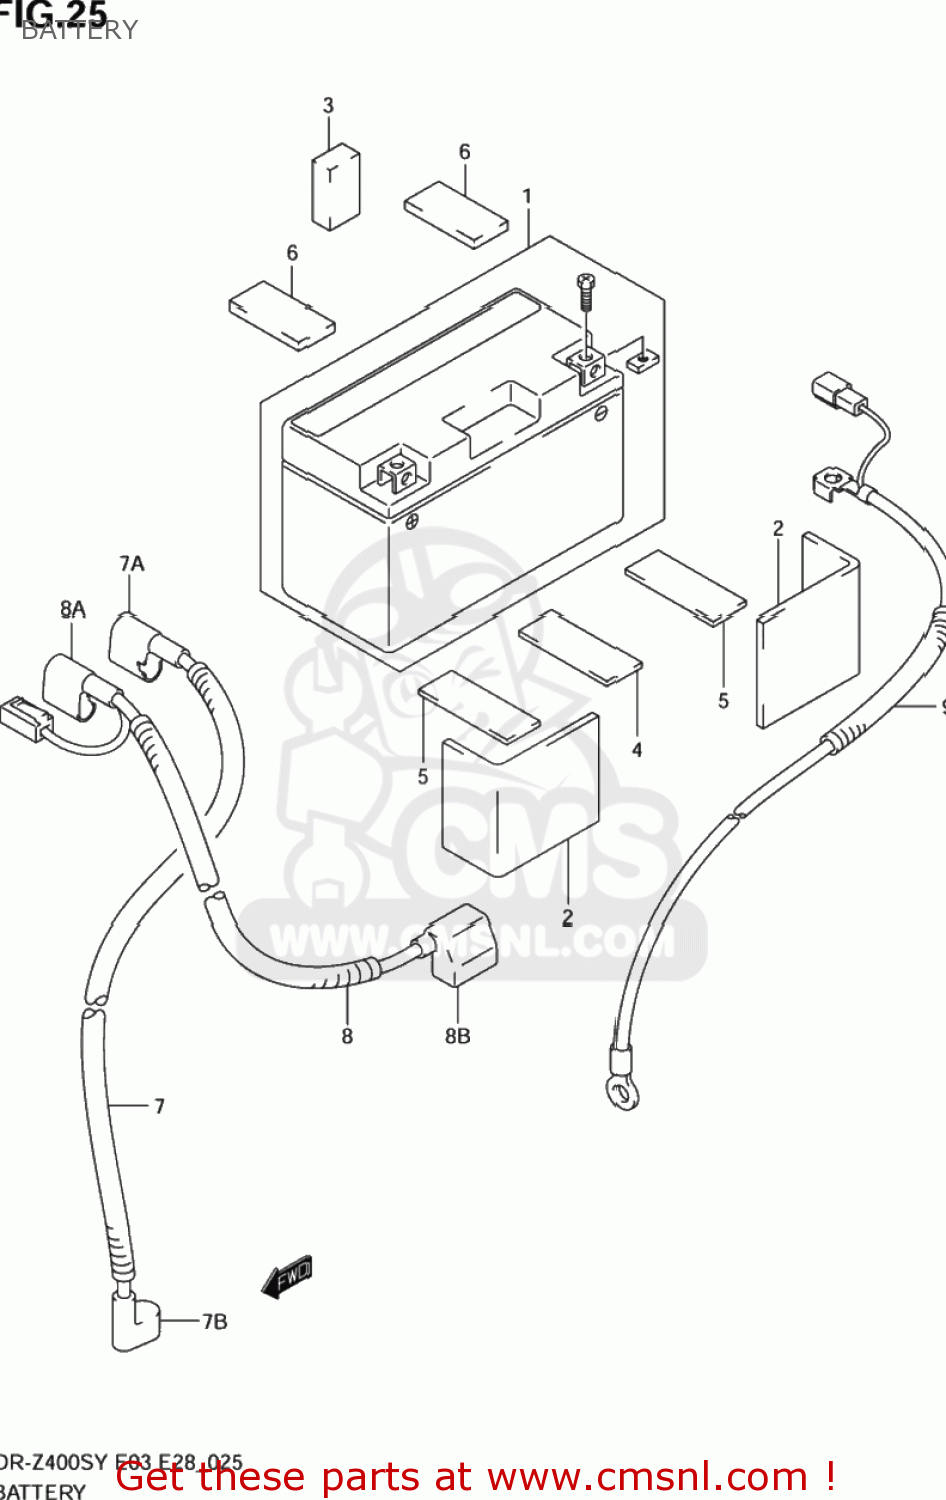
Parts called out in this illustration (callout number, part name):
1	BATTERY ASSEMBLY
2	PROTECTOR(170X95X3.0)
3	PROTECTOR,BATT
4	PROTECTOR(30X80X1)
5	PROTECTOR(80X80X2)
6	DAMPER,HEADLAMP HOUSING BRACKET
7	WIRE,STARTER MOTOR LEAD
7A	CAP,STARTER RELAY
7B	CAP,STARTER MOTOR
8	WIRE,BATTERY PLUS LEAD
8A	CAP,STARTER RELAY
8B	CAP,BATTERY PLUS
9	WIRE,BATTERY MINUS LEAD
